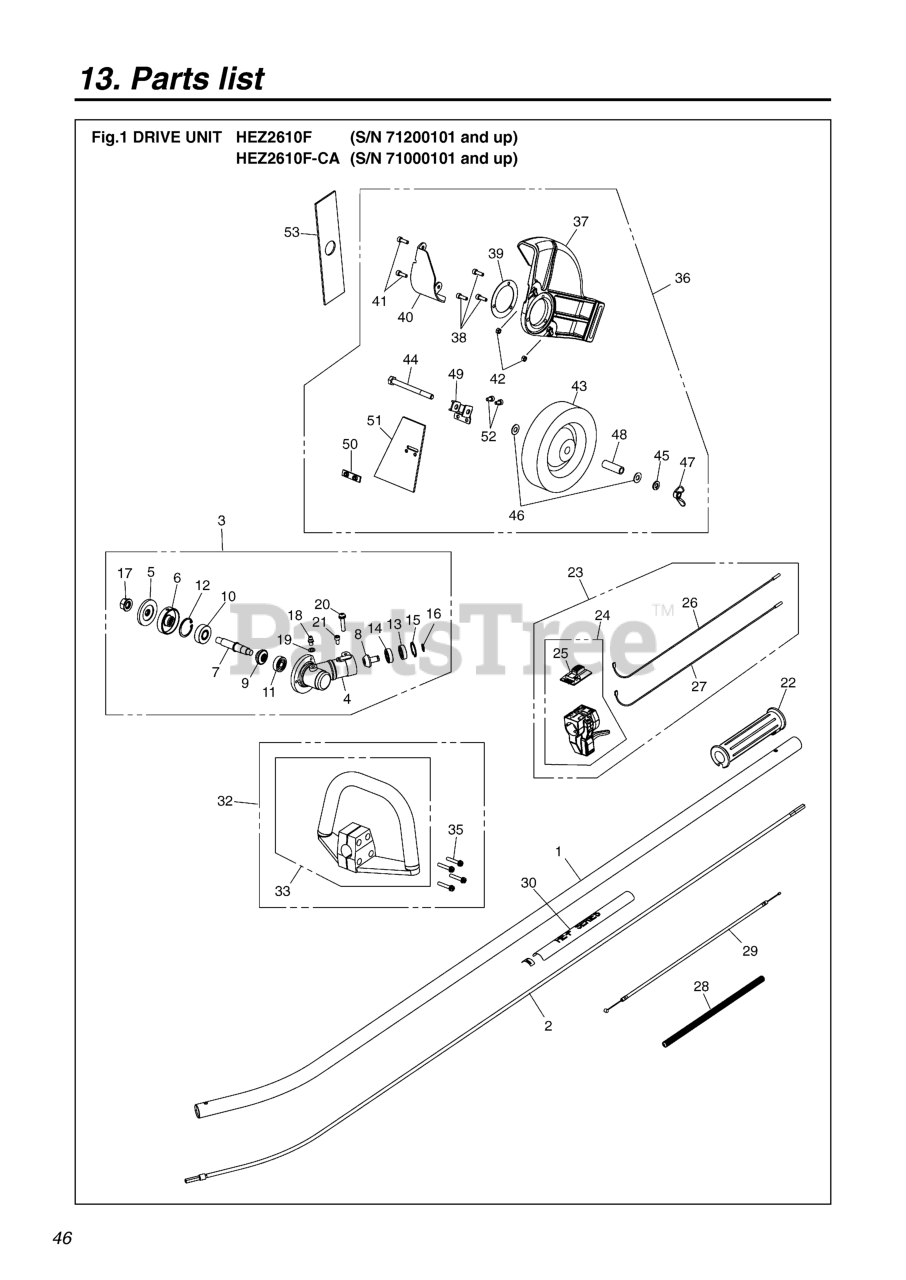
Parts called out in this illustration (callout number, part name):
1	PIPE COMP
2	SHAFT COMP
4	GEARCASE
5	HOLDER B
6	HOLDER A
8	PINION
9	GEAR
10	BEARING
11	BEARING
12	RING, SNAP, M32 x 1.2
13	BEARING (RPLS T3300-13531)
14	BEARING (RPLS T3403-13530)
15	RING, SNAP, M24 x 1.2
17	NUT
18	FITTING, GREASE
19	WASHER, M6 X .8
20	BOLT
21	BOLT, M5 X 10
22	GRIP
23	LEVER ASSY
24	LEVER
25	COVER COMP. (RP. 6110-14410-02)
26	CORD (A), BLACK
27	CORD (B), RED
28	TUBE (RPLS 4900-72141)
29	CABLE (RPLS 5580-83100)
30	NAME PLATE
32	HANDLE ASSY. (REPLACES -14001)
33	HANDLE T
35	SCREW
36	GUARD ASSY.
37	GUARD
38	BOLT (M5x0.8-16)
39	PLATE
40	PROTECTOR
41	BOLT (M5x0.8-16)
42	NUT, M5 X 4
43	WHEEL
44	BOLT
45	WASHER, SPRING
46	WASHER, PLANE(USE 01640-20816)
48	SLEEVE
49	BRACKET
51	RUBBER (FLAP)
52	BOLT, M5 X 10
53	BLADE, EDGER (RPLS 147315)
